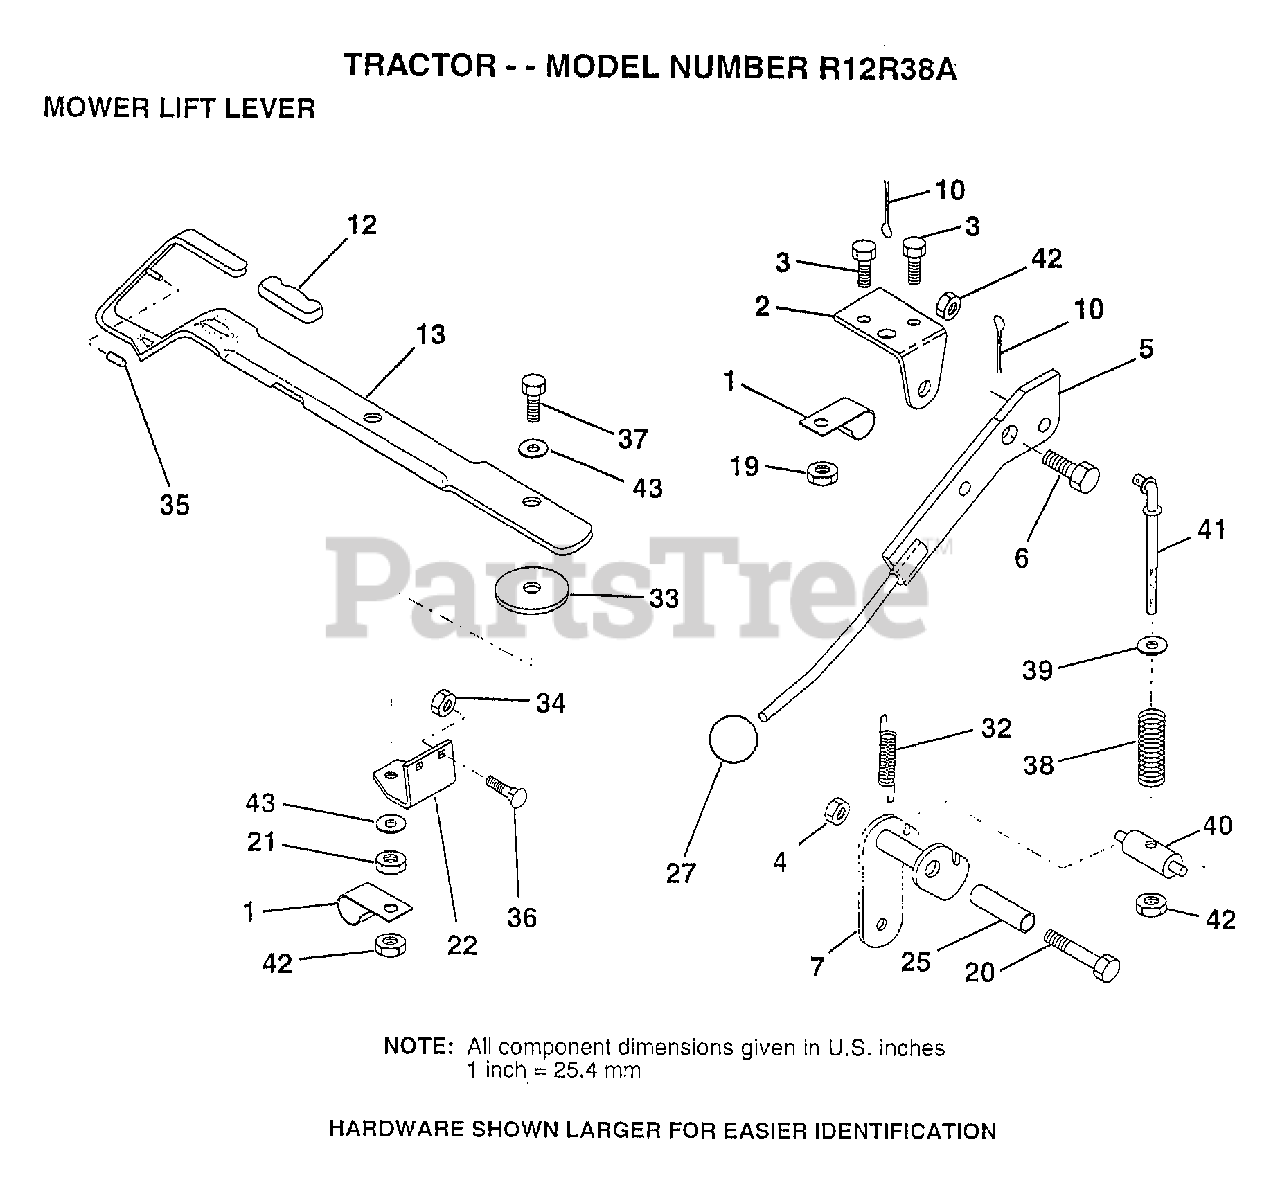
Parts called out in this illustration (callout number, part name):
1	"CLIP,INSULATOR"
2	BRKT CLUTCH
3	BOLT HXHD FIN
5	LEVER.ASM.CLUTCH
6	"BOLT, SHOULDER LT"
7	ARM.CLUTCH.ASM
10	COTTER PIN
12	HANDLE, LIFT LEVER
13	LEVER LIFT LR
20	BOLT
21	LOCKNUT
22	LIFT LEVER BRKT
25	TUBE SPACER
27	KNOB T(3/8 HOLE)
32	SPRING EXT
33	WASHER
34	NUT
35	VINYL CAP RED
36	BOLT
37	BOLT
38	COMP CLUTCH SPRNG
39	WASHER HYT
40	TRUNNION
41	ROD TENSION CLUTC
42	NUT
43	WASHER
